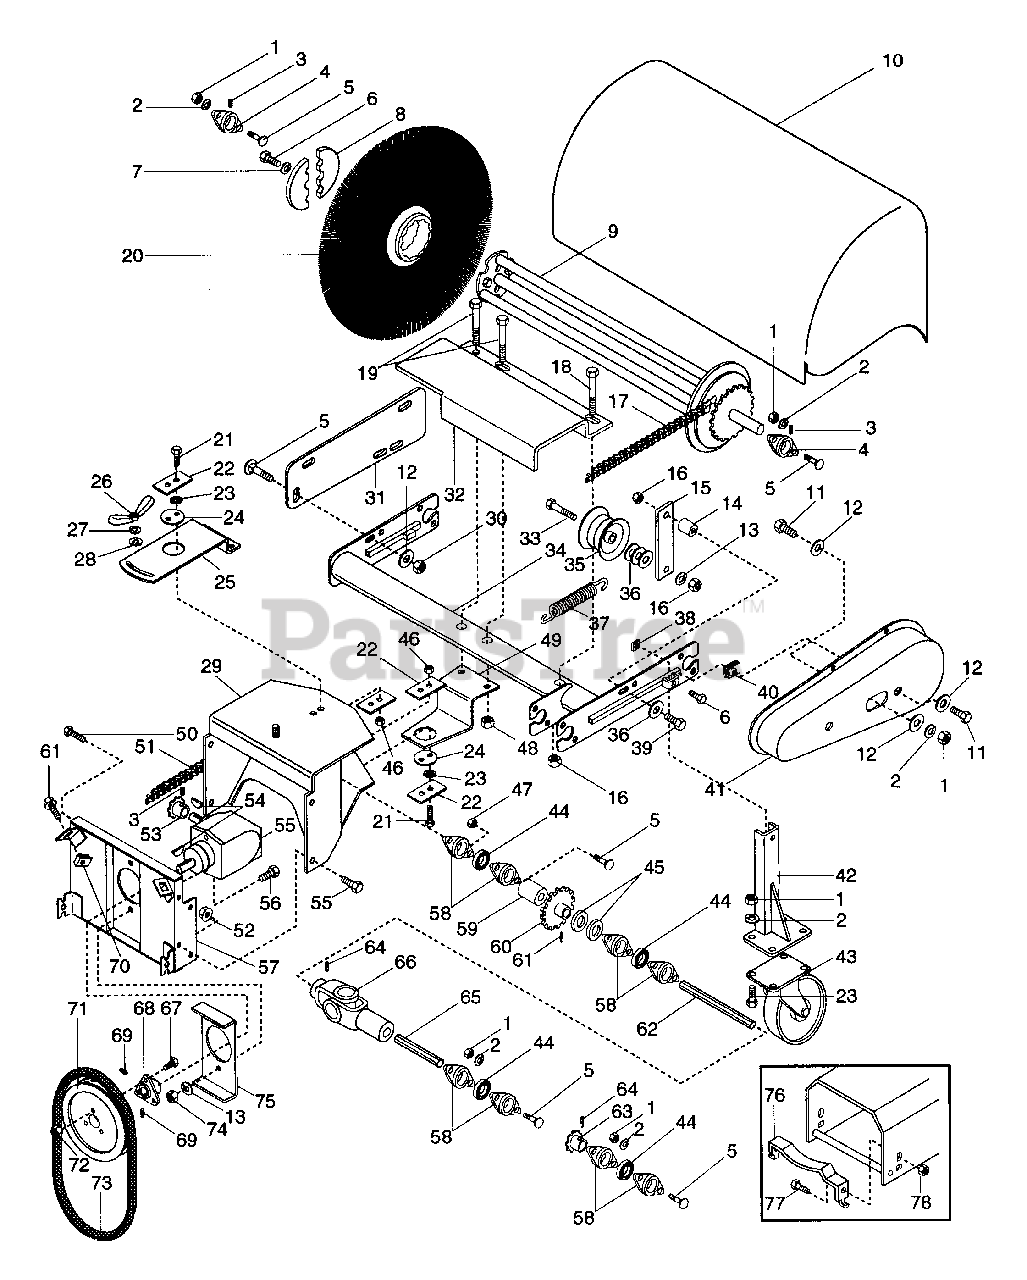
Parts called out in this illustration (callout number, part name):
1	NUT-HEX .312-18
2	WSHR-LK .312X.097 PL HVY
3	SCR-SET .25-20X.38 SKHCUPNL OH
4	BRG 1.00 BORE, SPHER. OD.
5	BLT-RDHDSQNK .31-18X.75 GR5 PL
6	BLT-HEX .50-13X1.00 PL GR2
7	WSHR-LK .500X.151 HVY PL
8	RETAINER PLATE (SET OF 2)
11	BLT-HEX .31-18X1.00 PL GR 2
14	BSHG-SLV .375X.437X.312
15	IDLER ARM
16	NUT-LK-CTR .375-16 GR A PL
17	CHAIN
18	BLT-HEX .38-16X3.00 PL GR2
19	BLT-HEX .38-16X3.50 PL GR5
20	POLY BRUSH ASSEMBLY
21	BLT-HEX .31-18X1.50 PL GR5
22	RETAINER
23	WSHR-LK-INT .313X.030 PL
24	PIVOT CENTER
25	TOP MOUNT PLATE
26	WING NUT
27	WSHR-FL-STL .390X.750X.125 PL
28	WSHR-LK .375X.130
29	ADAPTER FRAME
30	NUT-LK .312-18 GR A PL
31	HOOD STRAP
32	SHAFT GUARD
33	BLT-HEX .38-16X2.00 PL GR2
34	BRUSH FRAME
35	CHAIN TIGHTENER
36	WSHR-FL-STL .438X1.0X.083 PL
38	NUT-SQ .50-13
39	BLT-HEX .38-16X1.00 PL
40	NUT-SPEED U-TY .312-18
41	CHAIN SHIELD
42	CASTOR LEG
43	WHL, 5 DIA.
44	BRG-BALL .884HEXX52MMX1.07
45	WSHR-FL-STL 1.015X1.500X.125
46	NUT-LK-TOP .312-18 GR C PL
47	BLT-SCRHFWH .38-16X.75 PL
48	NUT-LK TOP .375-16 GR C YWZC
49	BOTTOM MOUNT
50	BLT-HEX .38-16X.75 PL GR2
51	CHAIN
52	NUT-LK-FLG .375-16 GR A PL
53	SPROCKET
54	KEY-WDRF .188X.75X.313 SAE 9
55	GEAR BOX ASSEMBLY
56	BLT-HEX .38-16X1.25 PL GR 2
57	MOUNTING PLATE
58	BEARING FLANGE
59	SPACER 1.006X1.307X.500
60	SPROCKET
61	PIN-ROLL .188X1.75
63	SPROCKET
64	PIN-ROLL .188X1.50
65	DRIVE SHAFT
66	JOINT, UNIVERSAL
67	BLT-SERRDHD SL .31-18X.75 YZ
68	HUB ASSEMBLY
69	SCR-SET .32-18X.38 SKHCUPNL OH
70	NUT-RETNR .38-16 TINRMAN
71	PLY-V 9.0 X 1.25 3BLT
72	NUT-FLG. .312-18 PL
73	V-BELT, 4L-RAW EDGE
74	NUT-HEX .375-16
75	STIFFENER PLATE
76	BELT RETAINER
77	BLT-HEX .25-20X.50 PL GR2
78	NUT-LK-CTR .250-20 PL
79	FLANGE, SPHERICAL 2"
